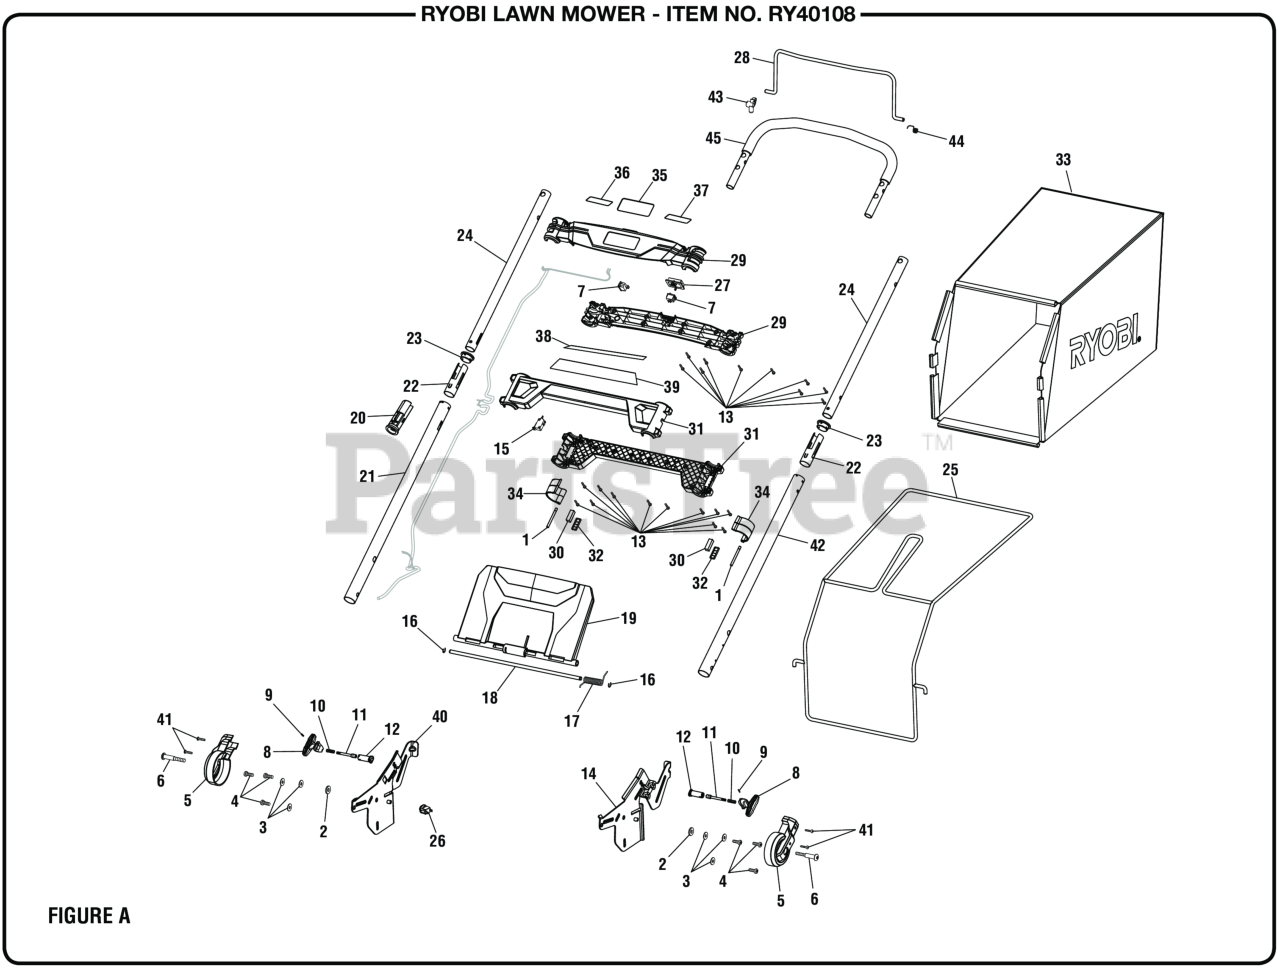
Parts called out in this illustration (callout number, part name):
1	Pin (Handle Lock Clip)
2	Washer (ID8.5 x OD20.5 x 2 mm x 2t)
3	Washer (1/4 in., Type A)
4	Screw (1/4-15 x 3/4 in., T30 Torx Pan Hd.)
5	Hinge Cover
6	Shoulder Screw (M8 x 60 mm, T40 Torx Hd.)
7	Stop Switch (Momentary Contact)
8	Adjustment Knob (Spring Pin)
9	Spring Pin
10	Compression Spring
11	Detent Pin
12	Spring Pin Housing
13	Screw (M4 x 18 mm, T20 Torx Pan Hd.)
14	Height Adjustment Bracket (Left)
16	RETAINING RING (EXTERNAL)
17	Torsion Spring (Rear Door)
18	Rear Door Axle
19	Rear Discharge Door
20	Switch Plug Housing
21	Lower Handle Tube (Right)
22	Handle Tube Bushing (Large)
23	Handle Tube Bushing (Small)
24	Upper Handle Tube
25	Bag Frame
26	TOGGLE SWITCH
27	Safety Switch Cover
28	Bail Handle
29	Upper Panel Assembly
30	Rubber Plate (Handle Lock Clip)
31	Lower Panel Assembly
32	Block (Handle Lock Clip)
33	Bag
34	Telescoping Latch
35	Logo Label
36	Start Label (Right)
37	Start Label (Left)
38	Lithium Label
39	Extended Handle Label
40	Height Adjustment Bracket (Right)
41	Screw (M4 x 20 mm, T20 Torx Pan Hd. S.T.)
42	Lower Handle Tube (Left)
43	Actuator Switch
44	Torsion Spring
45	Upper Handle & Foam Grip Assembly
